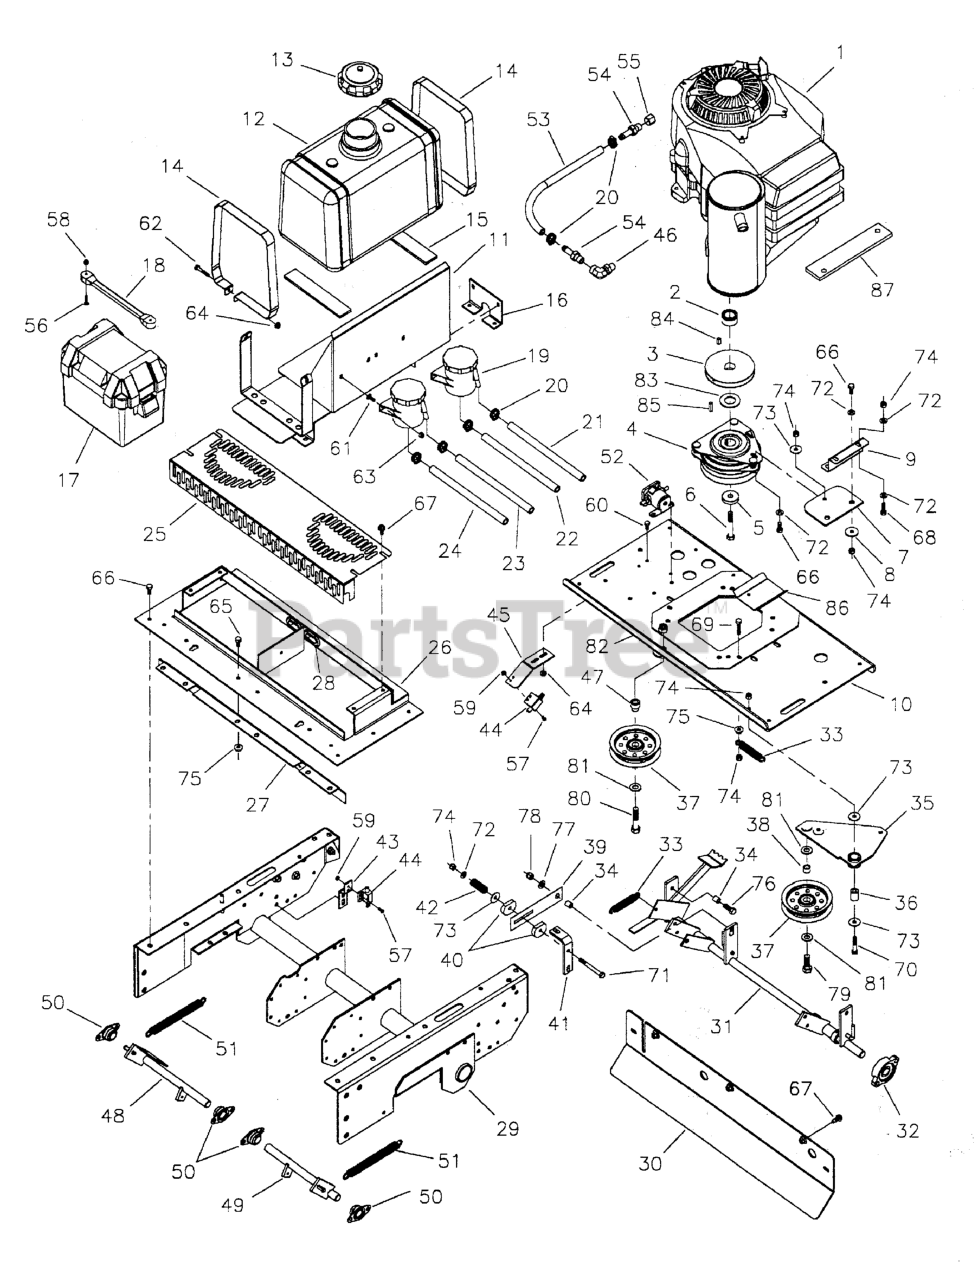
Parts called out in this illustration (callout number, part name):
2	CRANKSHAFT SPACER
2	SPACER, 1.00 X 1.50 X 1.12
2	SPACER, 1.13 x 1.75 x 1.50
3	PULLEY, Hydro Drive
3	PULLEY, DDSKAV23 Crankshaft
4	CLUTCH, Electric, 1" Shaft
4	CLUTCH, Electric, 1-1/8" Shaft
5	SPACER, .45 x 1.62 x .37
6	CRANKSHAFT BOLT, 7/16 x 3
6	CRANKSHAFT BOLT, 10 mm x 70 mm
6	CRANKSHAFT BOLT, 7/16 x 2-1/2
7	CLUTCH ANCHOR PAD
8	WASHER, Clutch Anchor
9	ANCHOR, Clutch
10	PLATE, Engine Deck
11	MOUNT, Fuel Tank (Electric)
11	MOUNT, Fuel Tank (Manual)
12	TANK, FUEL, PLASTIC, 5 GALLON W/ FUEL LINE
13	CAP, GASOLINE, VENTED
14	FUEL TANK STRAP
15	RUBBER PAD
16	Gas Tank Mount Leg
17	BATTERY BOX, W/ DRAIN HOLE
18	RUBBER STRAP
19	RESERVOIR, Hydraulic
20	CLAMP, #6 Hose
21	HOSE, 3/8" PUSH-LOCK, 37.00"
22	HOSE, 3/8 PUSH-LOCK, 26.00
23	HOSE, 3/8" PUSH-LOCK, 43.00"
24	HOSE, 3/8" PUSH-LOCK, 35.00"
25	FAN COVER
26	FAN SHROUD
27	SUPPORT, Engine Deck
28	GROMMET, 1-1/4"
29	ENGINE DECK
30	PLATE, Engine Deck Back
31	SHAFT, Control
32	BEARING, Flange
33	SPRING, Extension
34	SLEEVE
35	ASSM, MOUNT, GROUND DRIVE IDLER - RED
36	SPACER, .32 x .75 x 1.06
37	PULLEY, Backside Idler
38	INSERT, Bearing
39	PLATE, Friction
40	PUCK, Brake
41	SUPPORT, Engine Deck
42	SPRING, Compression
43	MOUNT, Switch
44	SWITCH, PLUNGER, N.C.
45	MOUNT, Switch
46	FITTING, 90 Degree, 3/8" NPT Swivel
47	INSERT, Bearing Shoulder
48	SHAFT, Brake-Right
49	SHAFT, Brake, Left
50	BEARING, Flange
51	SPRING, Extension
52	SOLENOID, Starter
53	1/2" Hose, 18" Long
54	FITTING, 3/8NPT-1/2" Hose, Straight
55	CAP, 3/8 NPT
56	SCREW, #10-24 X 1 RS, CZ
57	SCREW, #10-24 x 1/2
58	NUT, #10-24 Hex Nylon Lock
59	NUT, #10-24 Hex
60	HHCS, 1/4-20 X 0.625, GR5, ZINC/CLEAR
61	BOLT,1/4-20X0.750,GR5,STD NECK,SQ,ZC/CL
62	BOLT, 1/4-20 X 1-1/2
63	NUT, 1/4-20 HEX NYLON LOCK
64	NUT, 1/4-20 HEX SERR. FLANGE
65	BOLT, 5/16-18 x 5/8
66	BOLT, 5/16-18 X 3/4 GD5
67	BOLT, Self-Tapping, 5/16-18 x 3/4
68	BOLT, 5/16-18 X 1 GD5 YZ
69	BOLT, 5/16-18 x 1-1/2 TFL
70	BOLT, 5/16-18 x 1-3/4
71	BOLT, 5/16-18 x 3
72	WASHER, 5/16" SAE
73	WASHER, 5/16" Fender
74	NUT, 5/16-18 Hex Nylon Lock
75	NUT, 5/16-18 HEX SERRATED FLANGE (LARGE)
76	BOLT, 3/8-16 X 1" GD5 CZ
77	WASHER, 3/8 SAE
78	NUT, 3/8-24 Hex Nylon Lock
79	BOLT, 1/2-20 X 1-1/2, GD5 CZ
80	BOLT, 1/2-20 X 2-1/2" GD5 CZ
81	WASHER, 1/2 SAE
82	NUT, Hex, Nylon Lock, 1/2-20
83	WASHER, 1" SAE
84	KEY, 1/4" SQ. X 1-1/4
85	KEY, 1/4 SQ. X 1
86	PAN, Oil Drain
87	SPACER, Engine Block
